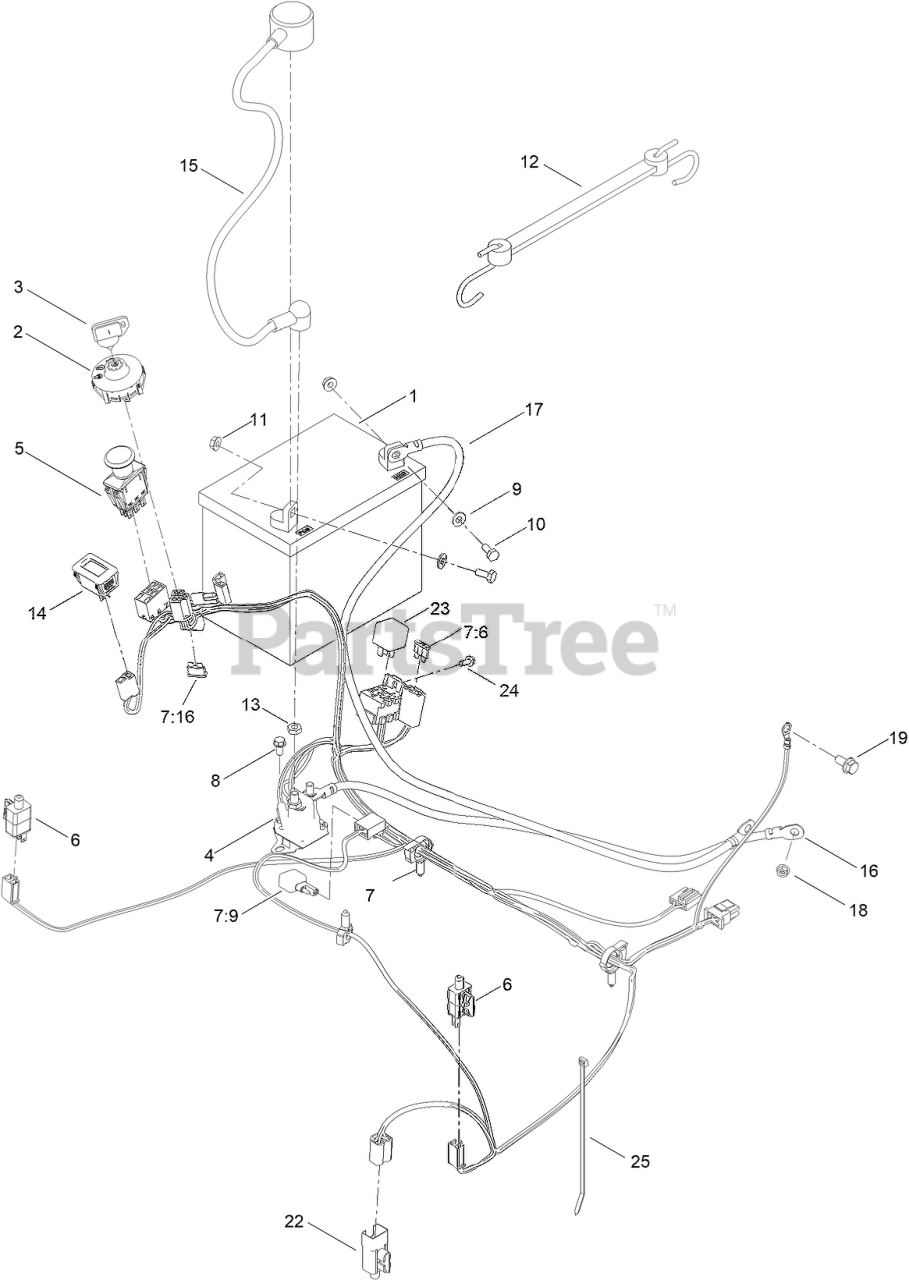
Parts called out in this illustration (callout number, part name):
1	BATTERY-DRY
2	SWITCH-IGNITION
3	KEY-IGNITION
4	SOLENOID
5	SWITCH-PTO
6	SWITCH
7	HARNESS-WIRE
7:6	FUSE-BLADE, 25 AMP
7:16	FUSE-BLADE, 15 AMP
8	SCREW-HWH
9	WASHER-FLAT
10	SCREW-HH
11	NUT-HF
12	HOLDDOWN-BATTERY
13	NUT-JAM
14	HOURMETER
15	CABLE-BATTERY, POSITIVE
16	CABLE-BATTERY, RD ASM
17	CABLE-BATTERY, NEGATIVE
18	NUT-HF
19	SCREW-HHF
22	SWITCH-REVERSE
23	RELAY
24	SCREW-TAPTITE
25	TIE-CABLE
